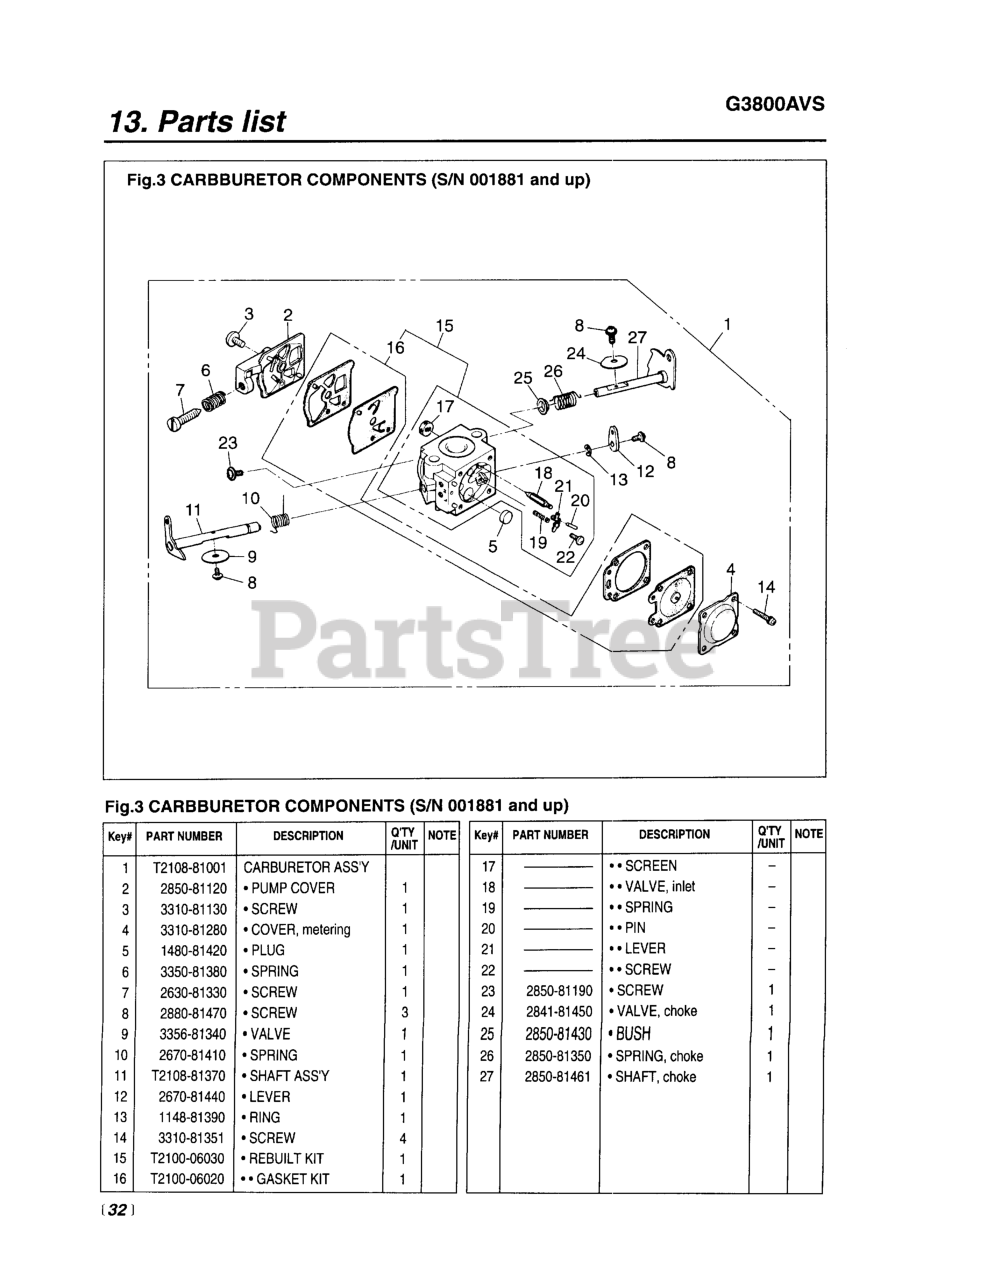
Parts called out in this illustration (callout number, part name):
1	CARBURETOR ASSY.
2	COVER, PUMP
5	PLUG, WELSH
6	SPRING, IDLE
8	SCREW (RPLS 3310-81360)
9	VALVE, THROTTLE
10	SPRING, RETURN
11	SHAFT ASSEMBLY, THROTTLE
12	VALVE, THROTTLE
14	SCREW ASSEMBLY
15	REBUILD KIT
16	KIT, GASKET (G3800AVS)
17	SCREEN
18	VALVE, INLET
20	PIN
21	LEVER
22	SCREW
26	SPRING, CHOKE
27	SHAFT, CHOKE
